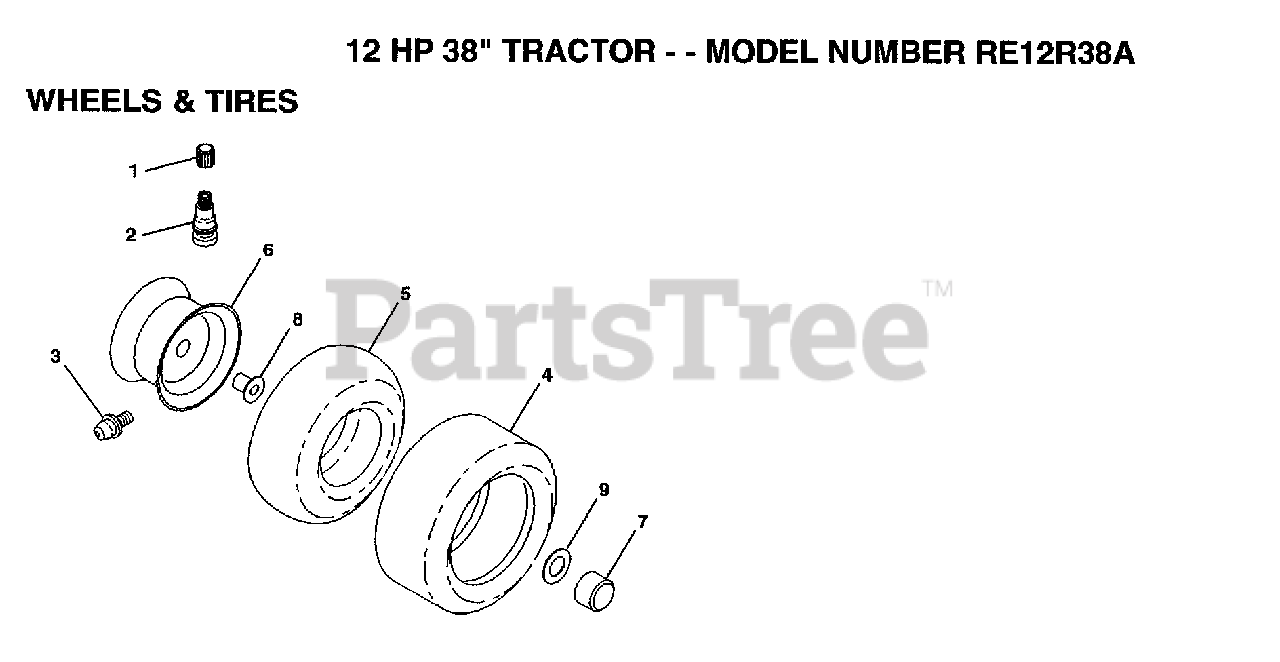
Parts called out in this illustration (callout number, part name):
1	VALVE CAP
2	VALVE STEM LT
3	FITTING LT
5	TUBE.5.3/4.5/6
7	Cap Axle Blk 1 50 X 1 00
8	FLANGE, BEARING
9	WASHER
